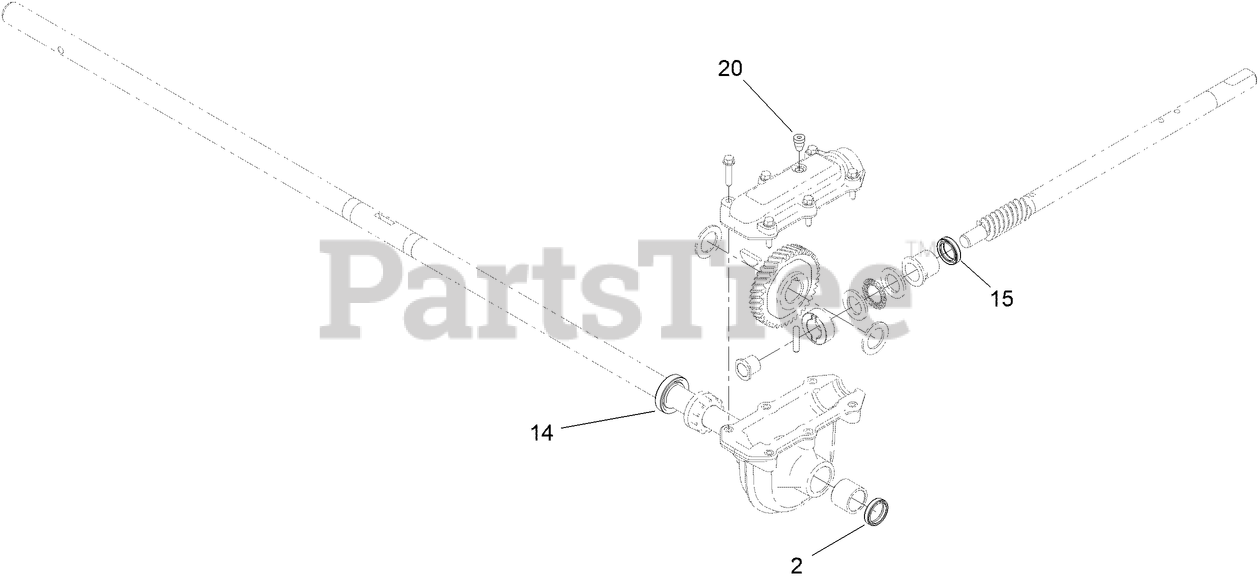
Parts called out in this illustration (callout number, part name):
2	SEAL-OIL
14	SEAL-OIL
15	SEAL-OIL
20	PLUG-OIL
